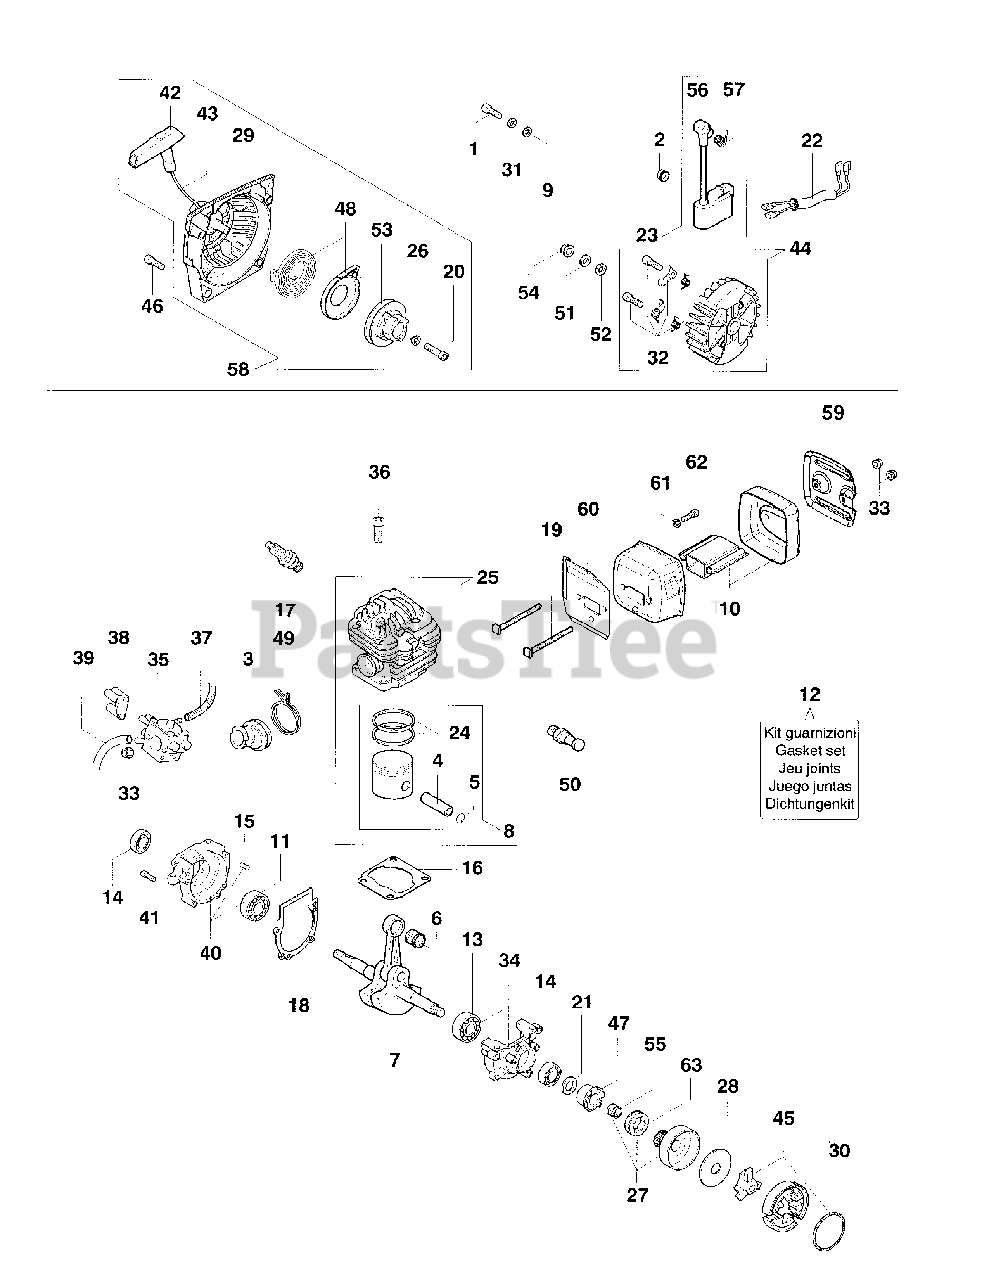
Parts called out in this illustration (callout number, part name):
8	COMPL.PISTON 045
10	MUFFLER COMPL.
14	SEALING RING
16	GASKET
17	SPARK PLUG
23	COIL
24	PISTON RING 045
25	COMPL.CYL. 045
27	CLUTCH DRUM
29	STARTER CASE
38	SCREW GUIDE
44	FLYWEEL
47	WORM GEAR
48	SPRING AND CASE
50	DECOMPRESSOR
58	STARTER ASSY
59	MUFFLER GUARD
63	RIM SPROCKET .325"
